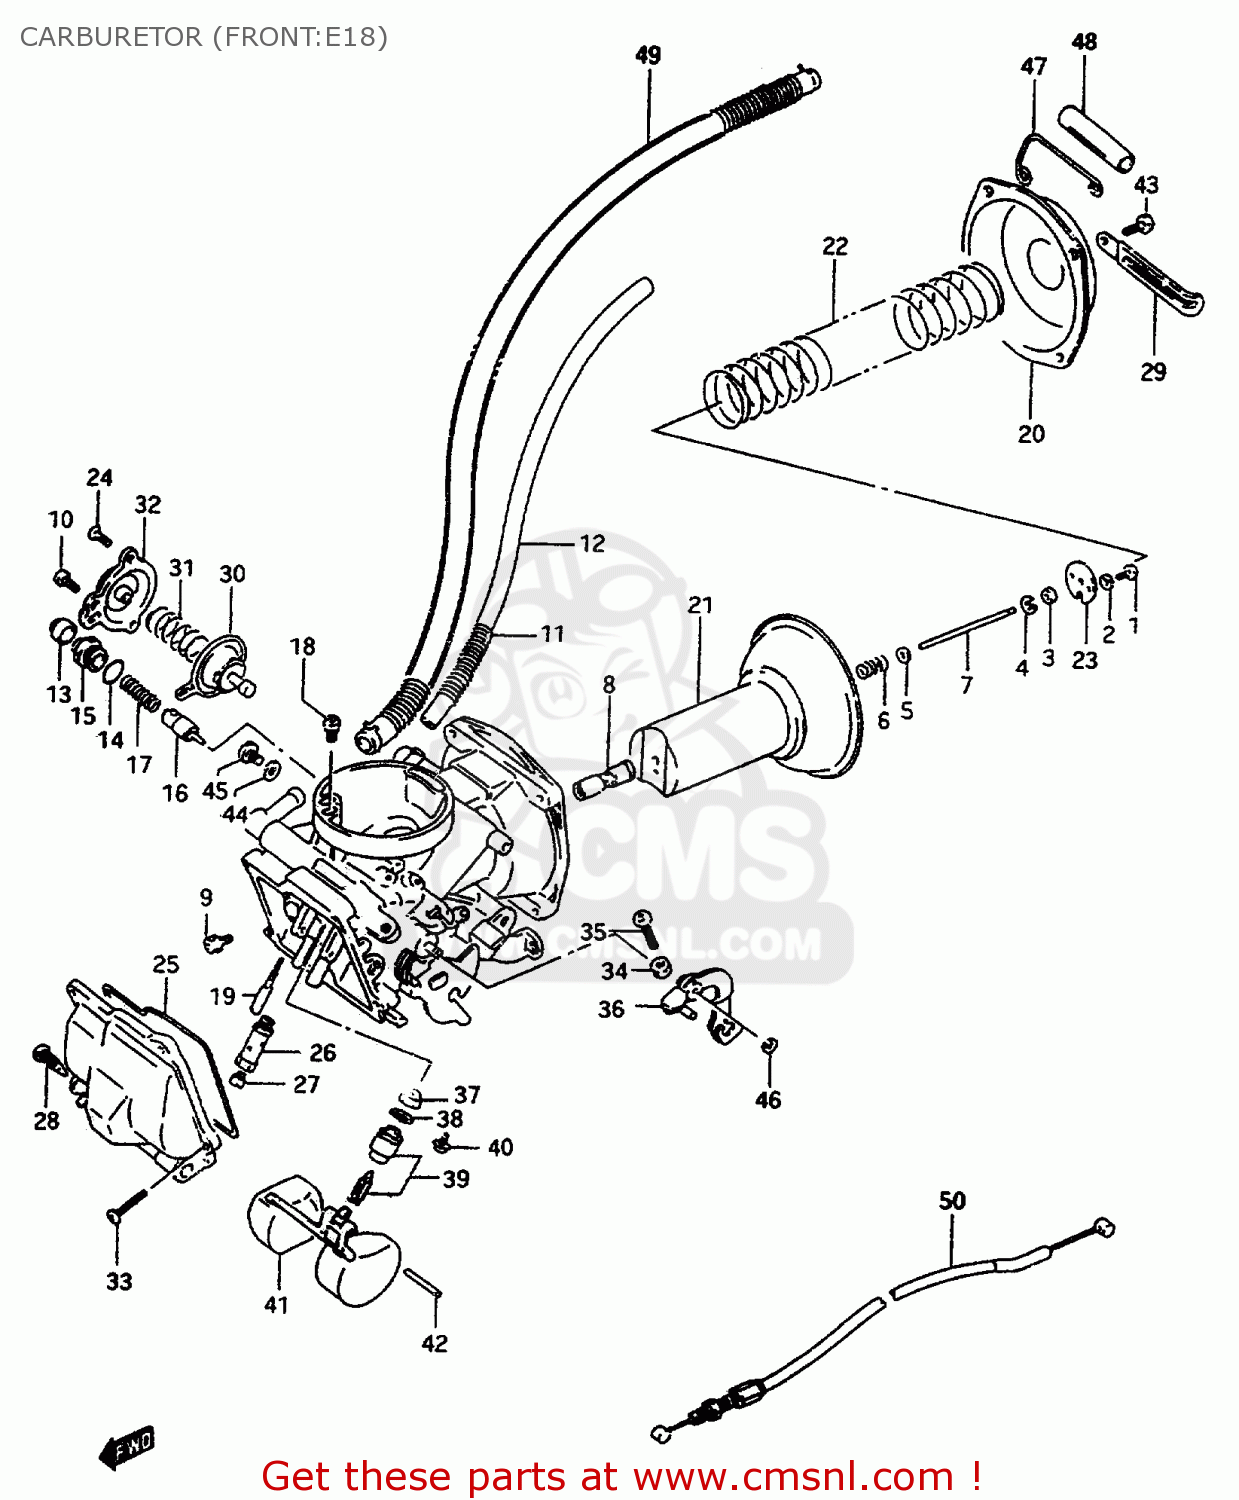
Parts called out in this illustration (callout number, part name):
1	SCREW
2	WASHER,LOCK
3	RING
4	CLIP
5	WASHER
6	SPRING
7	NEEDLE,JET (5032-3)
8	JET,NEEDLE(P-2)
9	SCREW
10	SCREW
11	SPRING
12	HOSE(5X8.2X600)
13	CAP
14	O RING
15	HOLDER,GUIDE
16	PLUNGER,STARTER
17	SPRING
18	JET,PILOT AIR,7
19	JET,PILOT(25)
20	COVER,DIAPHRAGM
21	DIAPHRAGM ASSY
22	SPRING,DIAPHRAGM
23	PLATE
24	SCREW,UPPER
25	O RING,FLOAT CHAMBER
26	HOLDER,MAIN JET
27	JET,MAIN(97.5)
28	SCREW,DRAIN
29	CLAMP(L:45)
30	DIAPHRAGM ASSY
31	SPRING
32	COVER
33	SCREW
34	NUT
35	SCREW
36	LEVER ASSEMBLY
37	FILTER
38	O-RING,NEEDLE VALVE
39	VALVE ASSY,NEEDLE
40	SCREW
41	FLOAT
42	PIN,FLOAT
43	SCREW
44	GASKET,DRAIN PLUG (NAS)
45	SCREW
46	E RING
47	CLIP
48	HOSE(6X10X600)
49	SCREW,PILOT
50	SPRING
51	O RING,PILOT AIR SCREW
52	WASHER
53	HOSE(6.5X11.5X600)
54	CABLE,IDLE SYNCRO
